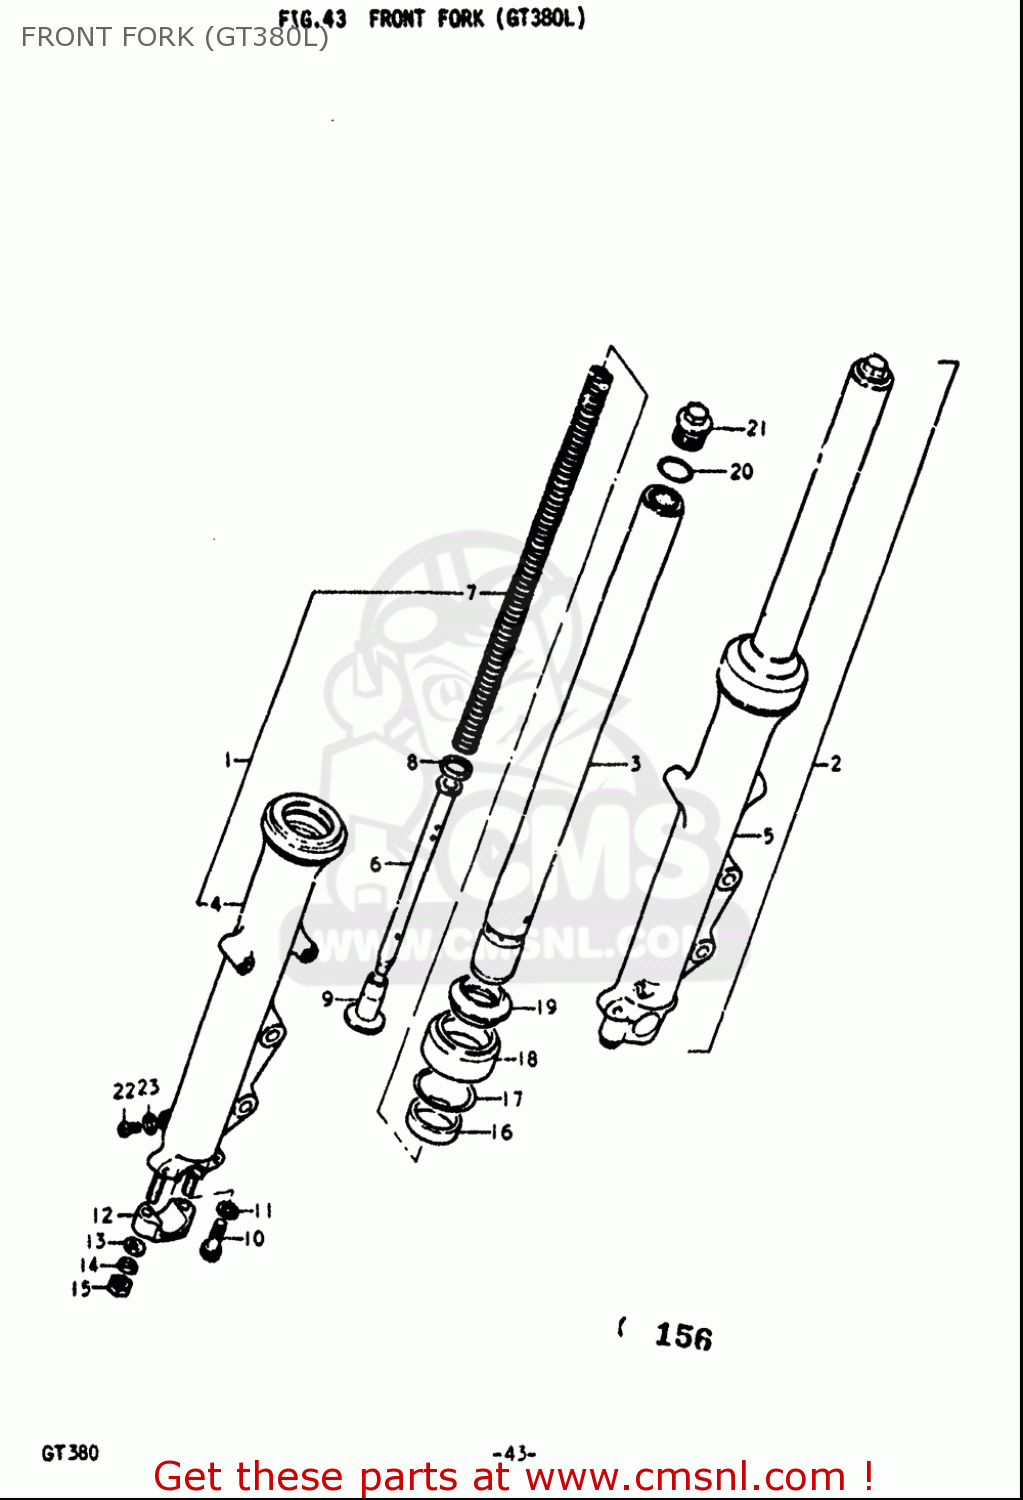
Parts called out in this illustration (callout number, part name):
10	BOLT(8X27)
11	GASKET (NAS)
12	HOLDER,AXLE
13	WASHER
14	WASHER,LOCK
15	NUT
16	SEAL,OIL
17	RING,OIL SEAL STOPPER
19	DUST SEAL
21	BOLT
22	SCREW 4X6
23	GASKET (NAS)
